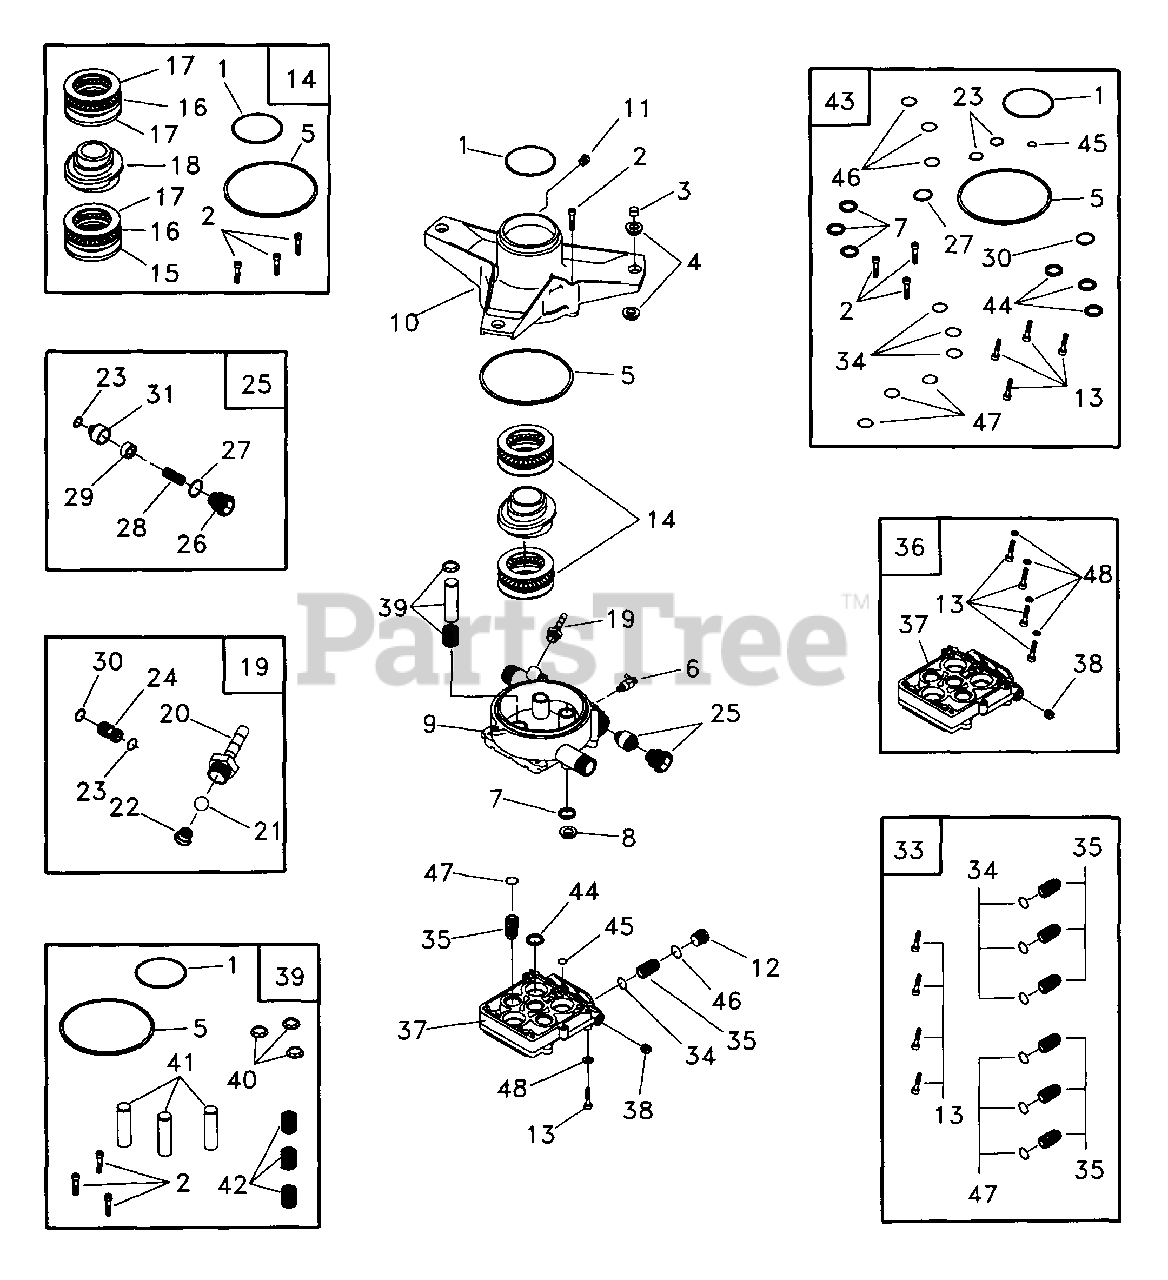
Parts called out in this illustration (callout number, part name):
1	O-RING, Engine Seal
2	SHCS, M6 - 1 x 25
3	SLEEVE, Grommet Spacer
4	BUSHING, Rubber Mount
5	O-RING, Housing Seal
6	THERMAL RELIEF, GPW-EG
7	SEAL, Oil Piston
8	SPACER, Pilot
9	HOUSING, Piston
10	ADAPTER, Engine
11	VALVE, 1/8 npt 1/5 PSI
12	CAP, Outlet Check Valve
13	SHCS, M6-1.0 x 35
13	SHCS, M6- 1.0 x 35
14	KIT, AXIAL CAM
15	WASHER, Brg. 36 x 65 x 6Thk
16	ASSY, Brg. Cage 45 x 65
17	WASHER, Brg. 45 x 65 x 1
18	CAM, Axial 5.6 7/8" SAE
19	KIT, CHEM INJECT
20	FITTING, Chem Inject
21	BALL, Chem Inject
22	SPRING, Chem Inject
23	O-RING, Venturi & Seat, Black
24	VENTURI, Chem Inject
25	KIT, UNLOADER
26	CAP, Unloader
27	O-RING, Unloader Cap
28	SPRING, Unloader
29	PISTON ASSY, Unloader
30	O-RING, Venturi, Yellow
31	SEAT, Unloader
33	KIT, CHECK VALVES
34	O-RING, Check Valve
35	ASSY, Check Valve
36	KIT, HEAD BRASS EG
37	HEAD, Pump
38	PLUG, 1/8-28
39	KIT, PISTON & SPRING
40	RETAINER, Piston Spring
41	PISTON, Dia. 15 x 65
42	SPRING, Piston Return
43	KIT, O-RING/SEAL 2300
44	SEAL, Double-Lip
45	O-RING, High Pressure Transfer
46	O-RING, Outlet CV Cap
47	O-RING, Check Valve, White
48	WASHER, M6 Flat
